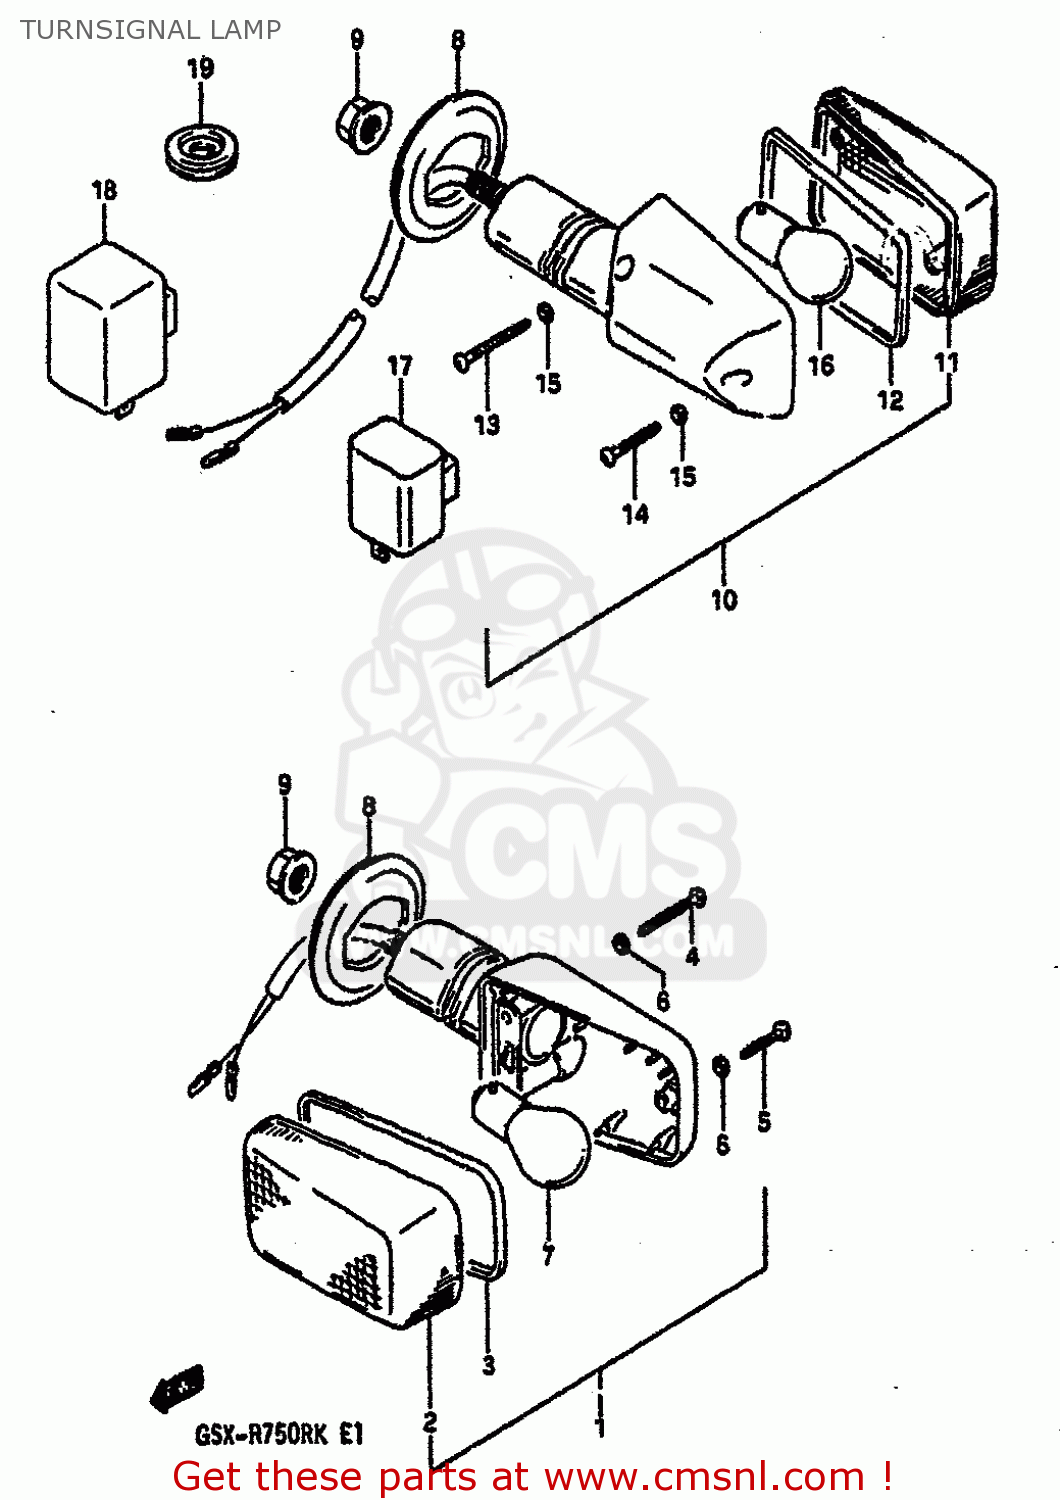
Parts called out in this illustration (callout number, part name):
1	LAMP ASSEMBLY,FRONT TURN SIGNAL
2	LENS
3	GASKET (NAS)
4	SCREW(3X30)
5	SCREW
6	GASKET (NAS)
7	BULB(12V21W)
8	GROMMET
9	NUT
10	LAMP ASSY,RR TURNSIGNAL
11	LENS
12	GASKET (NAS)
13	SCREW(3X30)
14	SCREW
15	GASKET (NAS)
16	BULB(12V21W)
17	RELAY ASSEMBLY,TURN SIGNAL
18	RELAY ASSY,TUR
19	GROMMET
